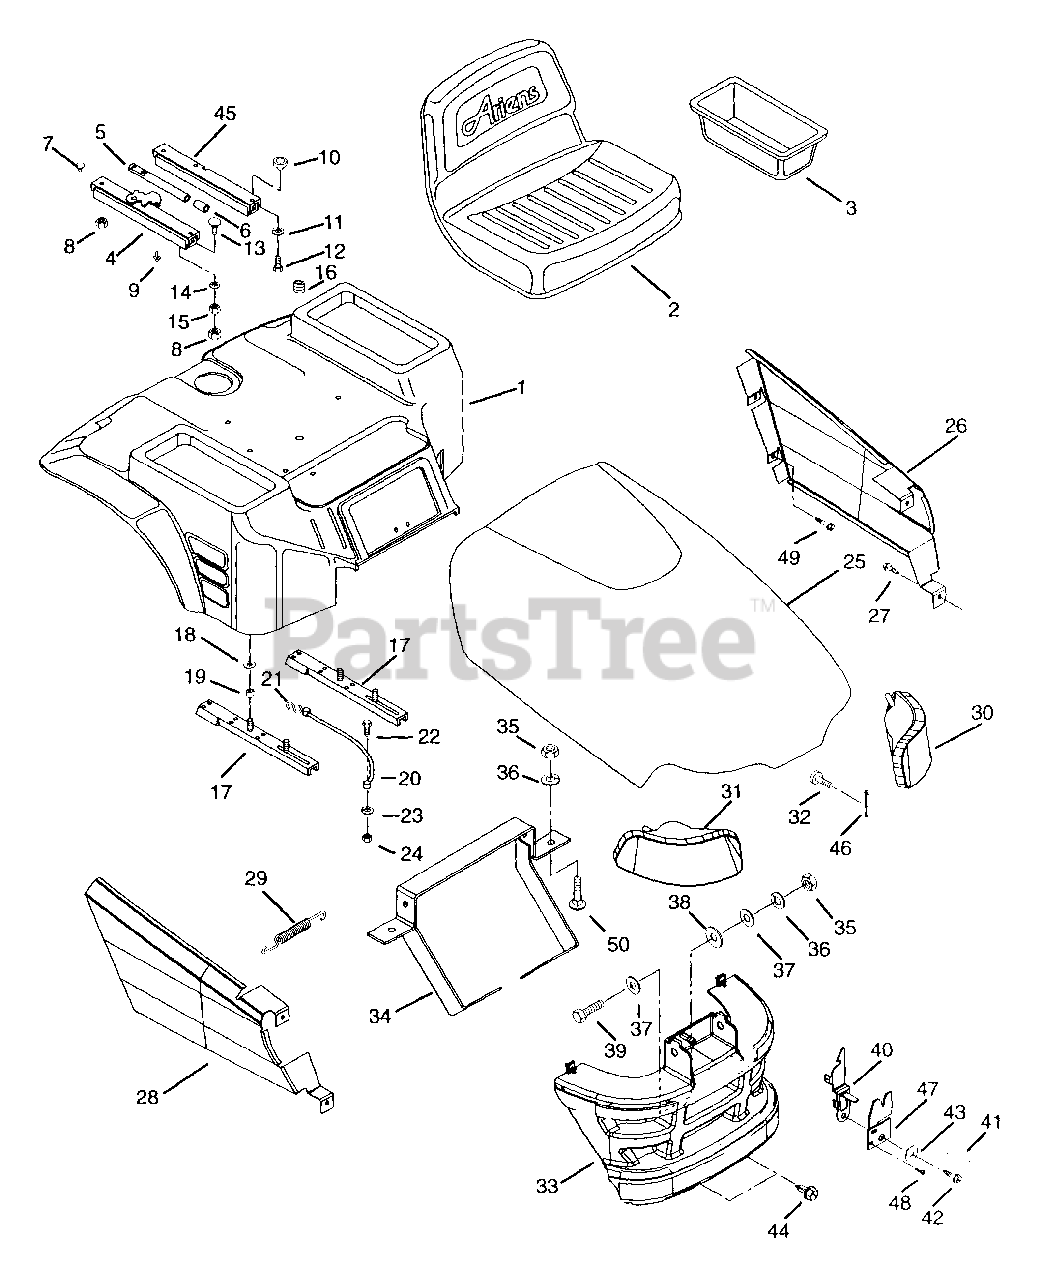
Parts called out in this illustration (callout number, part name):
1	REAR DECK
2	SEAT V-580
4	SEAT SLIDE R H
5	SEAT SLIDE HANDLE
7	SCR-CAP BTHD.31-18X.50 GR5 YZ
8	NUT-LK .312-18 GR A PL
9	NUT-LK 10-24 NY PL
10	SEAT SLIDE SPACER
11	WSHR-LK-EXT .313X.030 PL
12	SCR-MCH .31-18X1.00 CRRH PL
13	SCR-CAP BTHD.31-18X.875 GR5 PK
14	WSHR-LK .312X.097 PL HVY
15	NUT-HEX .312-18
16	GROMMET
17	SEAT SUPPORT
18	WSHR-FL-STL .390X.750X.125 PL
19	SPACER .380X.503X.281
22	SCR .25-20X.75 TS PH PL
23	WSHR-LK .250X.077 HVY PL
24	NUT-HEX .250-20 PL
25	HOOD WITH DECALS
26	SIDE PANEL- LH
27	SCR-TAP 12-16X.500 HI-LOTPHBL
28	SIDE PANEL- RH
29	SG-TENS .035X.45X2.75 WLD 3.5
30	HEADLIGHT- LH
31	HEADLIGHT- RH
32	PIN, CLEVIS .243/.248X1.50 YWZ
33	GRILLE
34	MOUNT - GRILLE
35	NUT-HEX .312-18
36	WSHR-LK .312X.097 PL HVY
37	WSHR-FL-STL .328X1.0X.094 PL
38	WSHR-FL-NYL .390X1.000X.062
39	BLT-HEX .31-18X1.00 PL GR5
40	HOOD LATCH
41	GRIP .062 X .375 X 1.000 RE
42	SCR-TAP 12-24X.50 HWH TR BLACK
43	WSHR-FL-STL .281X1.250X.048 BL
44	SCR-TAP .312-18X.50 HWH TR BL
45	SEAT SLIDE L H
46	PIN-COTR .09X.75 PL
47	LOCATOR, HOOD
48	SCR-TAP 10-12X.50 CRPH PL A BL
49	SCR-TAP 10-12X.62 CRPH PL A
50	BLT-RDHDSQSHNK .38-16X1.00 PL
